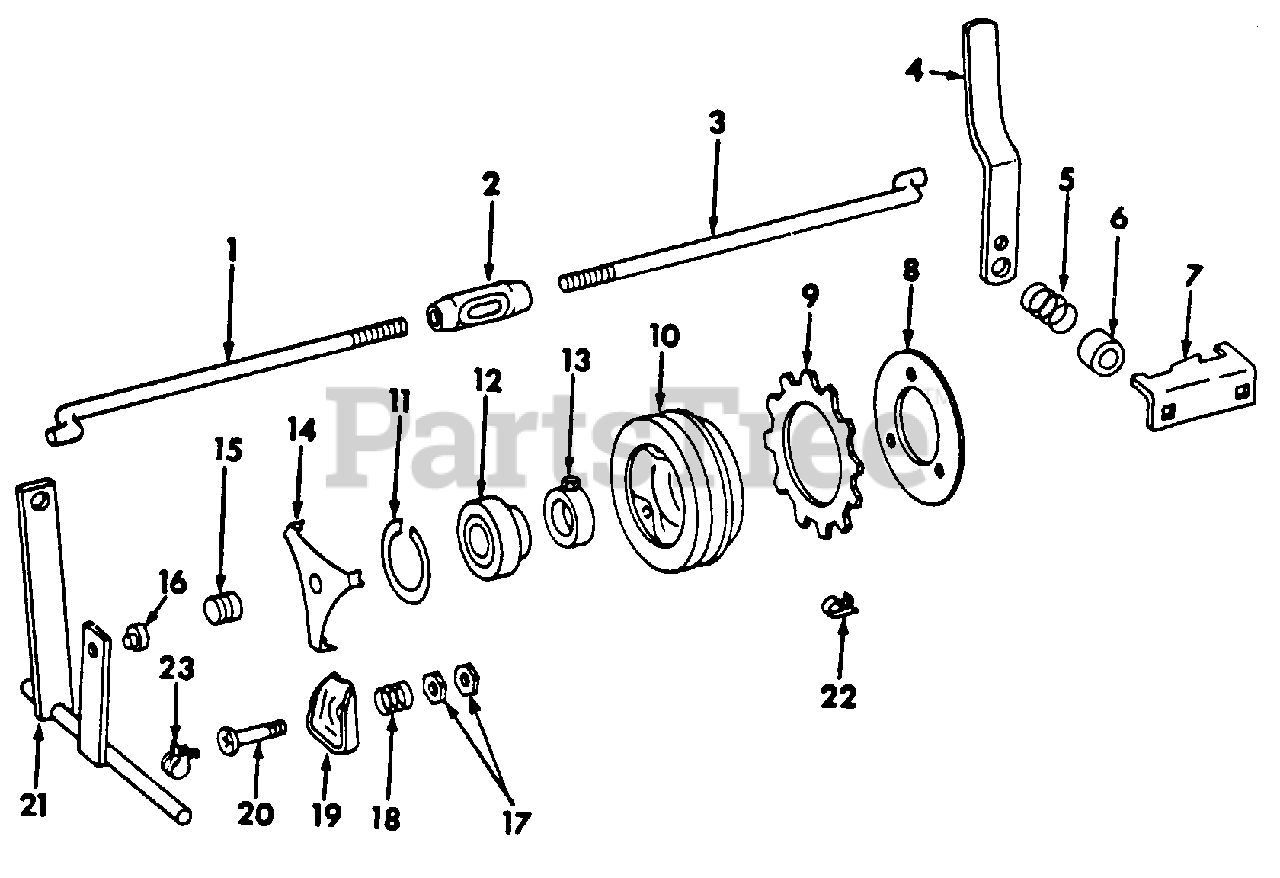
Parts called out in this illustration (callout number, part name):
2	Turnbuckle, Rod
3	Rod, Rear Clutch
4	Lever, Handle
5	Not used in this application
6	Not used in this application
7	Latch, Handle
8	Plate, Pressure
9	Disc, Friction
10	Pulley, Mower Actuating
11	Ring, Snap 2.197 O.D., For Pulley
12	Bearing, Ball
13	Collar w/Set Screw & Lock Nut, Brg
14	Spring, Pressure
15	Button, Thrust
16	Button, Wear
17	Nut, 1/4-28 Hex Jam
18	Spring, Compression
19	Lever, Throw-Out
20	Screw, Special Machine
21	Shaft, Clutch
22	Spring, Friction Disc
23	Clamp, Locating
